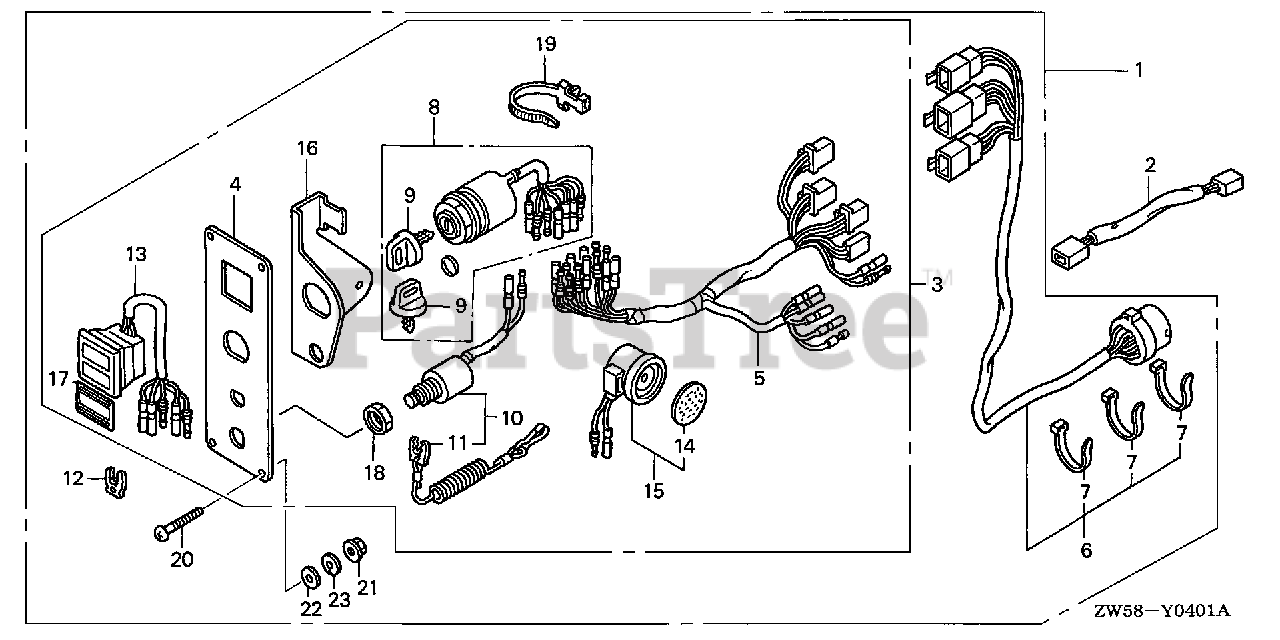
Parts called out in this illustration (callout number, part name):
1	PANEL KIT, SWITCH (SINGLE)
1	PANEL KIT, SWITCH (DUAL)
2	HARNESS ASSY., POWER TRIM-TILT FOR DUAL: QTY = (2)
3	PANEL ASSY., CONTROL (2-LED)
4	PANEL, CONTROL FOR DUAL: QTY = (2)
4	PANEL, CONTROL
5	HARNESS ASSY., SWITCH PANEL FOR DUAL: QTY = (2)
6	CABLE ASSY., SWITCH PANEL
7	TIE, CABLE (2.4X92) (NATURAL) FOR DUAL: QTY = (6)
8	SWITCH ASSY., COMBINATION FOR DUAL: QTY = (2)
9	KEY ASSY., COMBINATION SWITCH (35100-ZV5-003 ONLY) FOR DUAL: QTY = (4)
10	SWITCH ASSY., EMERGENCY STOP
11	WIRE, EMERGENCY FOR DUAL: QTY = (2)
11	WIRE, EMERGENCY
12	CLIP, EMERGENCY LOCK
13	LAMP ASSY., INDICATION (2-LED) FOR DUAL: QTY = (2)
14	PLATE, TURN SIGNAL BUZZER FOR DUAL: QTY = (2)
15	BUZZER, WARNING FOR DUAL: QTY = (2)
16	BRACKET, BUZZER FOR DUAL: QTY = (2)
17	MARK, SWITCH PANEL FOR DUAL: QTY = (2)
18	NUT, HEX. (16MM) FOR DUAL: QTY = (2)
19	BAND, WIRE HARNESS (150MM) (NATURAL) FOR DUAL: QTY = (2)
20	SCREW, PAN (5X40) FOR DUAL: QTY = (8)
21	NUT, FLANGE (5MM) FOR DUAL: QTY = (8)
22	WASHER, PLAIN (5MM) FOR DUAL: QTY = (8)
23	WASHER, SPRING (5MM) FOR DUAL: QTY = (8)
